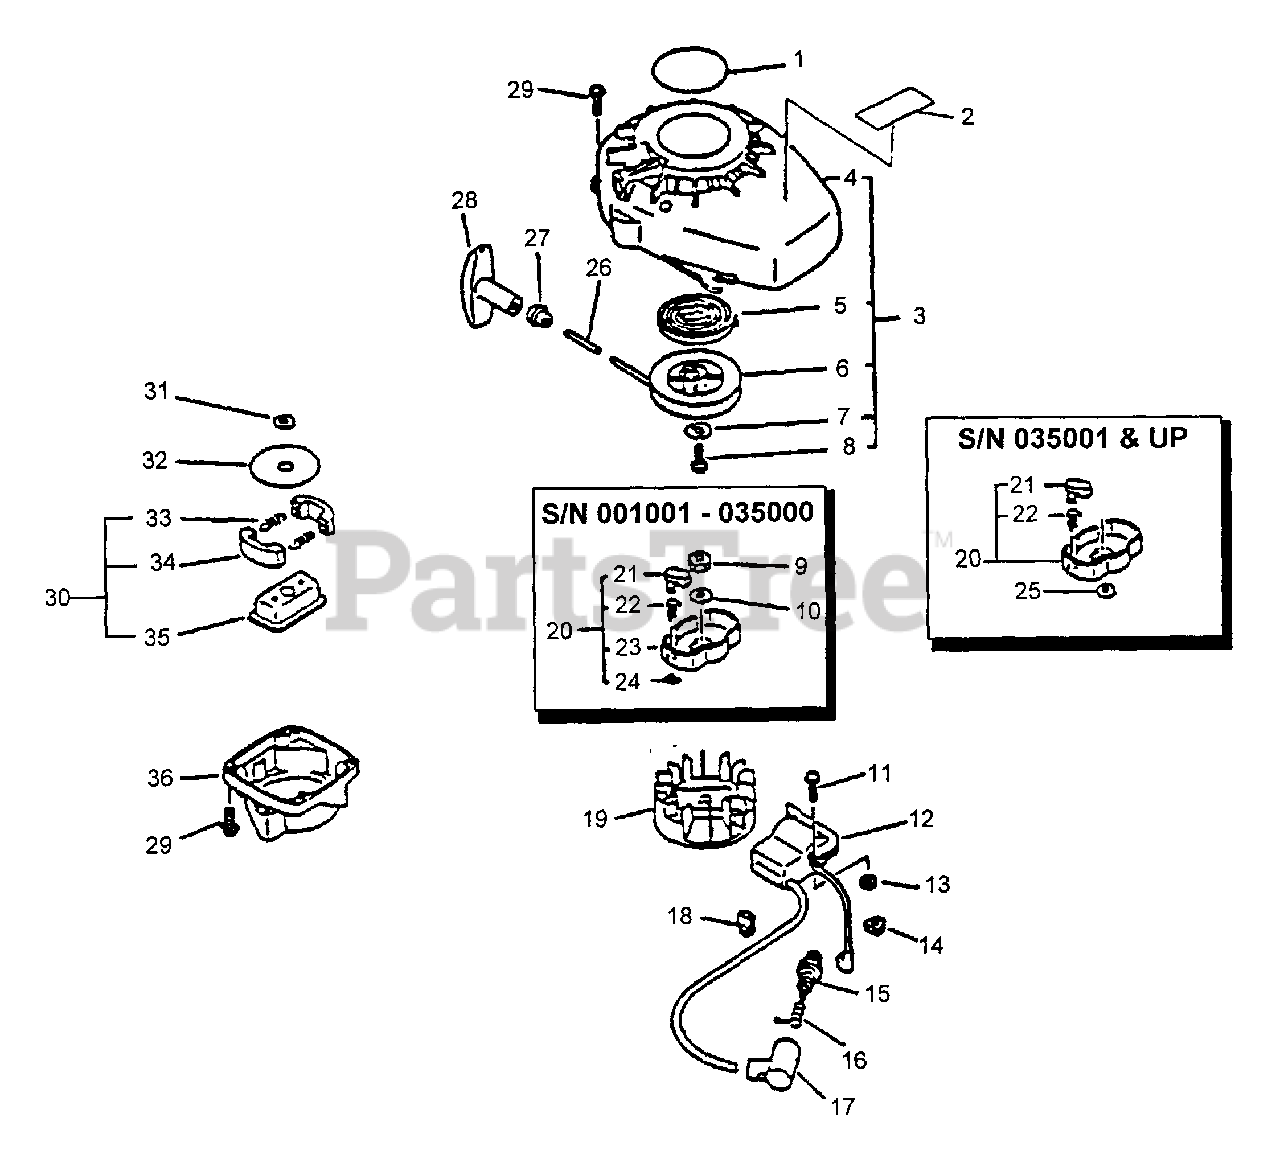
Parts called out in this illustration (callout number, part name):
1	LABEL - ECHO
1	LABEL, ECHO
1	LABEL, HC-1500
2	LABEL, MODEL
2	LABEL - MODEL
2	LABEL - CAUTION
3	STARTER ASSY
4	CASE, STARTER
5	SPRING, RECOIL
6	REEL, ROPE
7	WASHER
9	NUT 8×1.25
10	WASHER 8.5×16×1.2
11	SCREW 4×22
12	COIL, IGNITION
13	WASHER
15	SPARK PLUG - BPM6A
15	SPARK PLUG - BPMR6A
15	SPARK PLUG - BPM-7Y
16	TERMINAL, SPARK PLUG
17	CAP, SPARK PLUG
19	FLYWHEEL
20	STARTER PAWL ASSY
20	PAWL ASSY, STARTER
21	PAWL, STARTER
22	SPRING, RETURN
23	CATCHER, PAWL
24	E-RING 4
25	WASHER, SPRING 8
26	ROPE, STARTER
27	GUIDE, ROPE
28	GRIP, STARTER
29	SCREW 4×16
29	BOLT 4×16
30	CLUTCH ASSY
31	WASHER, CLUTCH
32	PLATE, CLUTCH
33	SPRING, CLUTCH
34	SHOE, CLUTCH
35	BOSS, CLUTCH
36	HOUSING, CLUTCH
